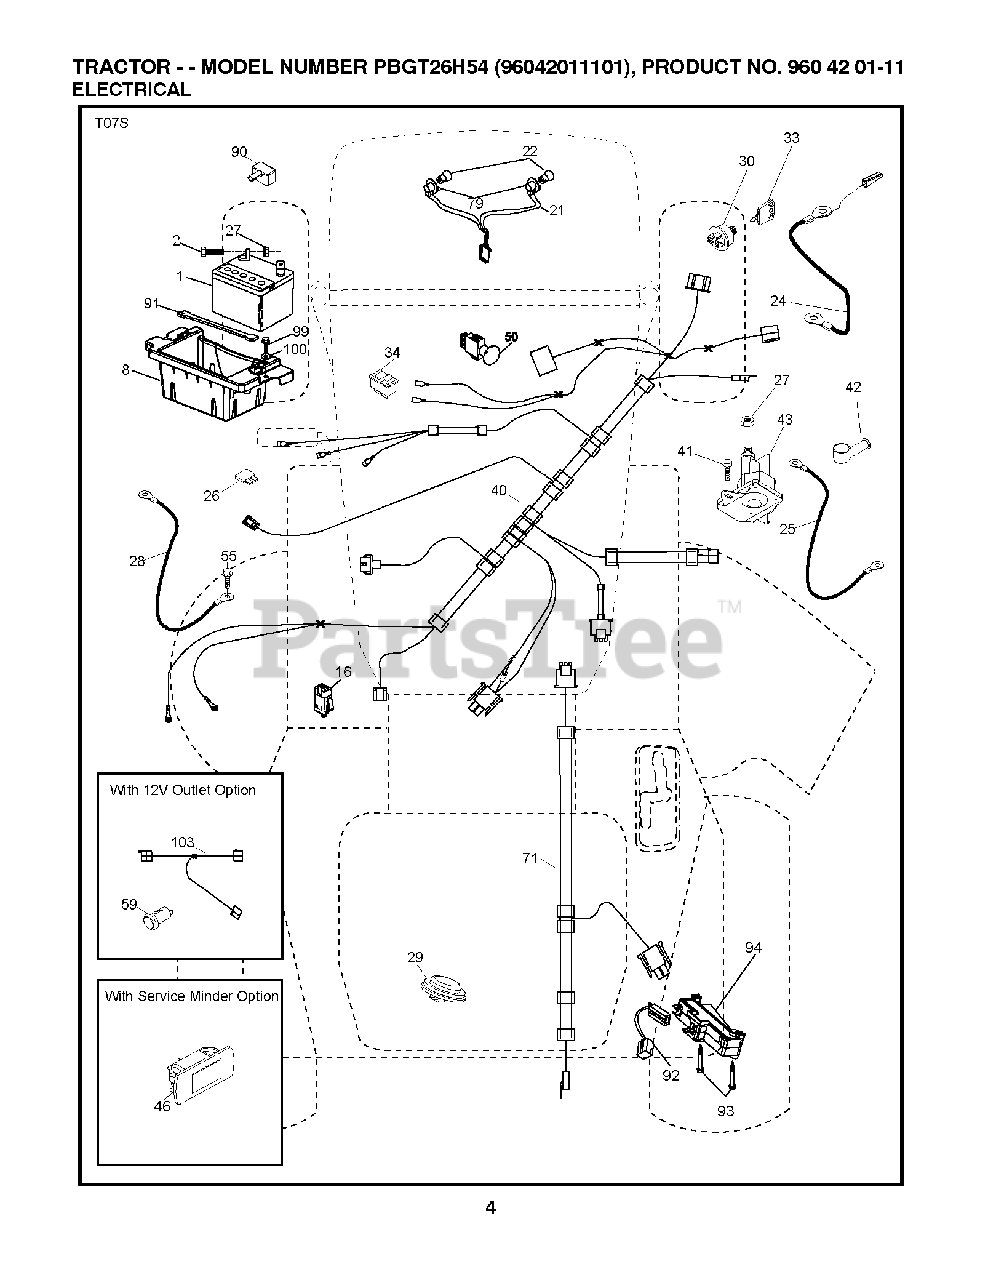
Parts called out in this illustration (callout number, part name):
1	REPL BY 532 12 38-99
2	BOLT.HEX.1/4.X.3/4.DICHROMATE
8	BOX.BATTERY.MOUNT.FRONT.LT
16	SWITCH INTERLOOK PUSH-IN
21	HARNESS ASSY LIGHT
22	LIGHTBULB
24	CABLE.BATT.POS.WIRE.TG.DA SOL
25	CABLE.STARTER.6G.BL/RED.17.5
26	FUSE 20AMP
27	NUT
28	CABLE GROUND 6 GA 21" 90T BLK
29	SWITCH.SEAT.DELTA.OPC.
30	SWITCH.IGN.DELTA.W.LGH.ROS
33	KEY.CHAIN.BLISTER.PACK.GEN.USA
34	SWITCH LT
40	HARNESS.IGN.DASH.HUQ/P
41	SCREW
42	TERMINAL COVER
43	SOLENOID.W/BRASS.PLUNGER
46	GUAGE.SRVCMNDR.HRMTR.
50	PTO SWITCH
55	SCREW 5/16"
71	HARNESS-CHASSIS SUB
79	BULB HOLDER ASM.
90	COVER.TERMINAL.BATTERY
91	STRAP.BATTERY.MOUNT.FRONT
92	HARNESS.PIGTAIL.CONSLE
93	SCREW.PLASTITE
94	MODULE.REVERSE.ROS
99	SCREW HEXWSHR 1/4-20X3/4
